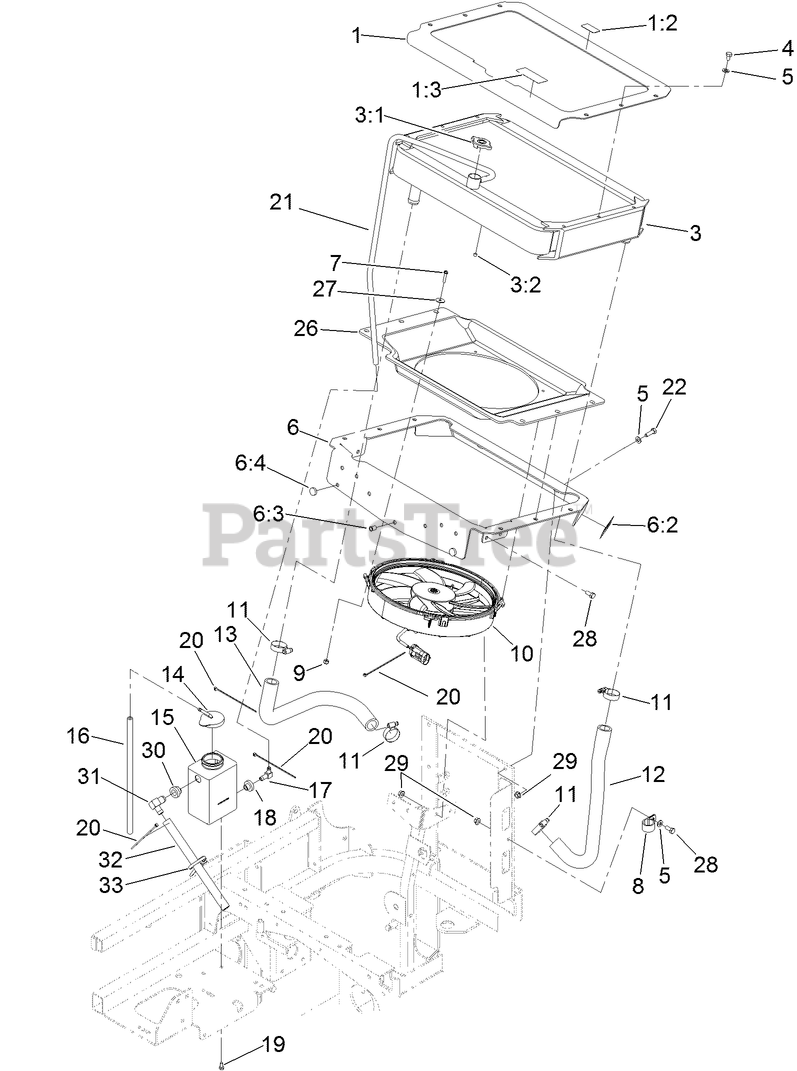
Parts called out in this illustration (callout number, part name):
1	TOP RADIATOR PLATE ASM
1:2	DECAL-SURFACE, HOT
1:3	DECAL-ANTIFREEZE
3	RADIATOR ASM
3:1	CAP-RADIATOR
3:2	PLUG-PIPE
4	SCREW-HH
5	WASHER-PLAIN
6	BOTTOM RAD PLATE ASM
6:2	DECAL-FAN, RADIATOR
6:3	NUT-CLINCH
6:4	BUMPER
8	CLIP-LOOM
9	NUT-LOCK, HH
10	FAN-HI PERFORMANCE
12	HOSE-RADIATOR, LH
13	HOSE-RADIATOR, RH
14	CAP-TANK, OVERFLOW
15	TANK-OVERFLOW
16	HOSE-LINE, FUEL
19	SCREW-HH
20	TIE-CABLE
21	HOSE-OVERFLOW
22	SCREW-HH
26	SHROUD
27	WASHER
28	SCREW-HH
29	NUT-HF
31	FITTING-ELBOW
32	HOSE-OVERFLOW
33	TIE-PLASTIC
